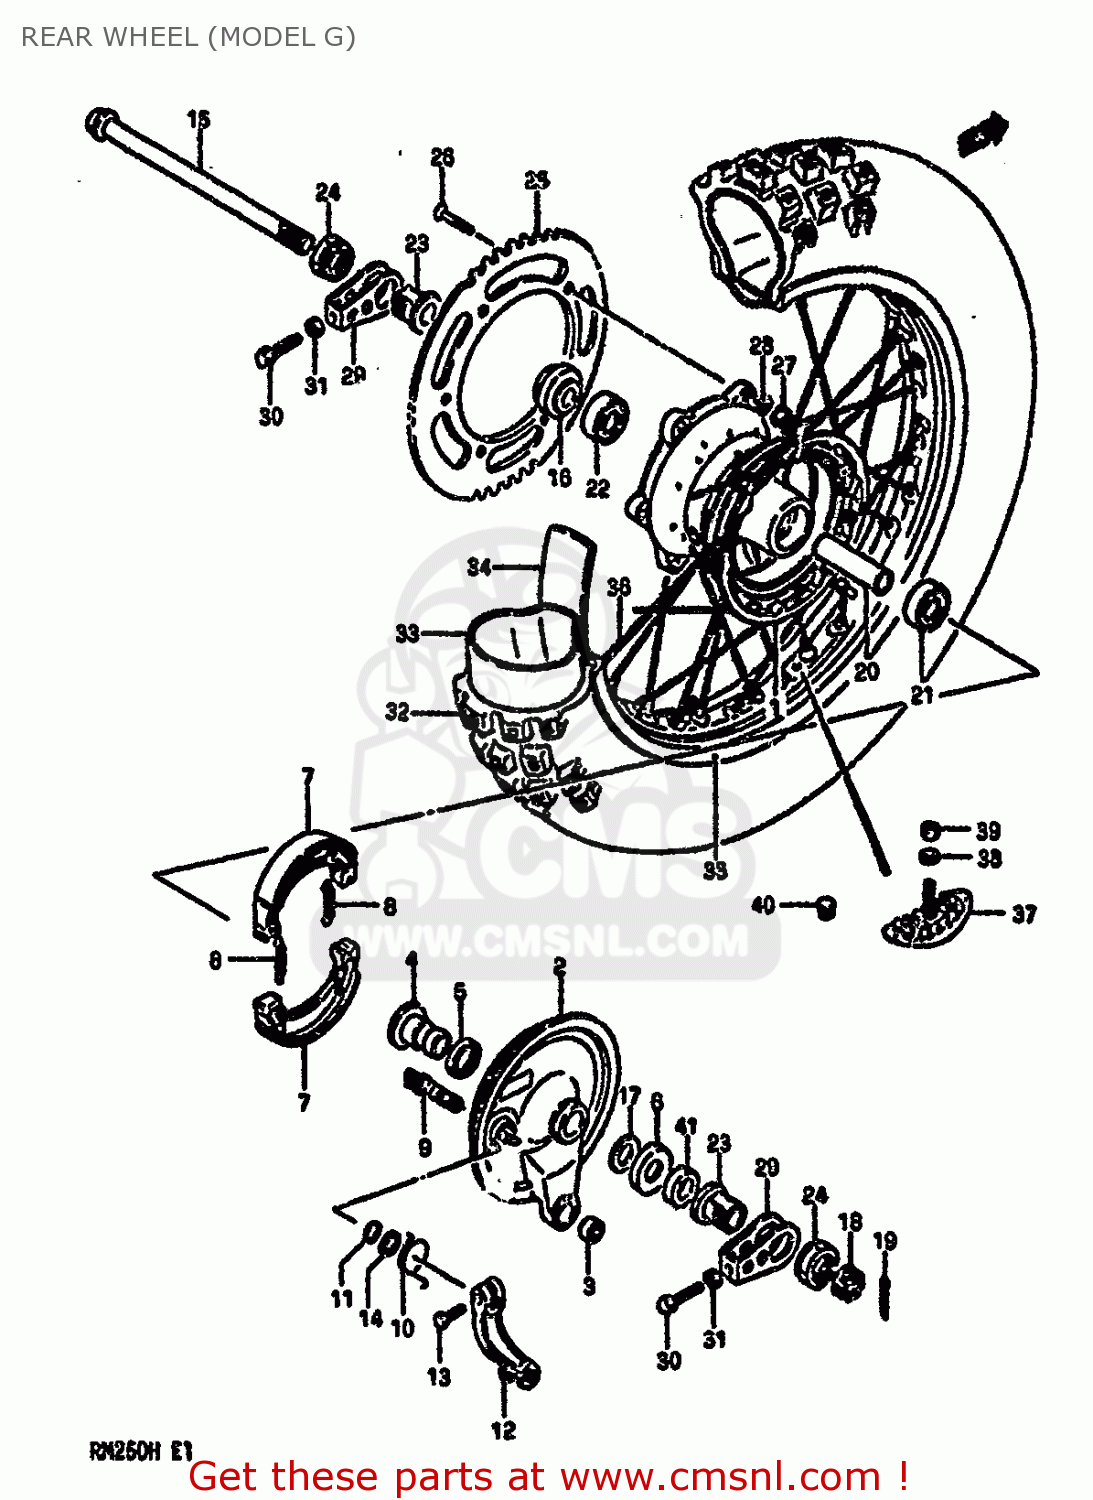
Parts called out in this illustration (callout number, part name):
1	DRUM,REAR HUB
2	PANEL SET
3	SPHERICAL BRNG,TORQUE LINK
4	SPACER,REAR HUB PANEL
5	SEAL,OIL(24X31X5)
6	CVR,RR BRAKE AHR PNL DUST SEAL
7	SHOE,BRAKE
8	SPRING,BRAKE SHOE
9	CAM,FR BRAKE
10	SPRING
11	O RING(D:2.5,ID:11.4)
12	LEVER,RR BRAKE CAM
13	BOLT
14	WASHER(12.5X20X1)
15	AXLE,REAR
16	SPACER COMP,REAR AXLE
17	WASHER
18	NUT
19	PIN,COTTER
20	SPACER,REAR HUB BEARING
21	BEARING
22	BEARING
23	SPACER,CHAIN ADJUSTER
24	NUT
25	SPROCKET,REAR
26	SCREW(8X40)
27	NUT
28	WASHER
29	ADJUSTER,CHAIN
30	BOLT(8X43)
31	NUT
32	TIRE
33	TUBE,INNER
34	PROTECTOR,WHEEL,INNER
35	RIM,REAR WHEEL (2.15X18)(A
36	SPOKE ASSY, REAR
37	STOPPER,BEAD
38	WASHER
39	NUT 8MM
40	CAP(OD:12)
41	SPACER,AXLE RH
